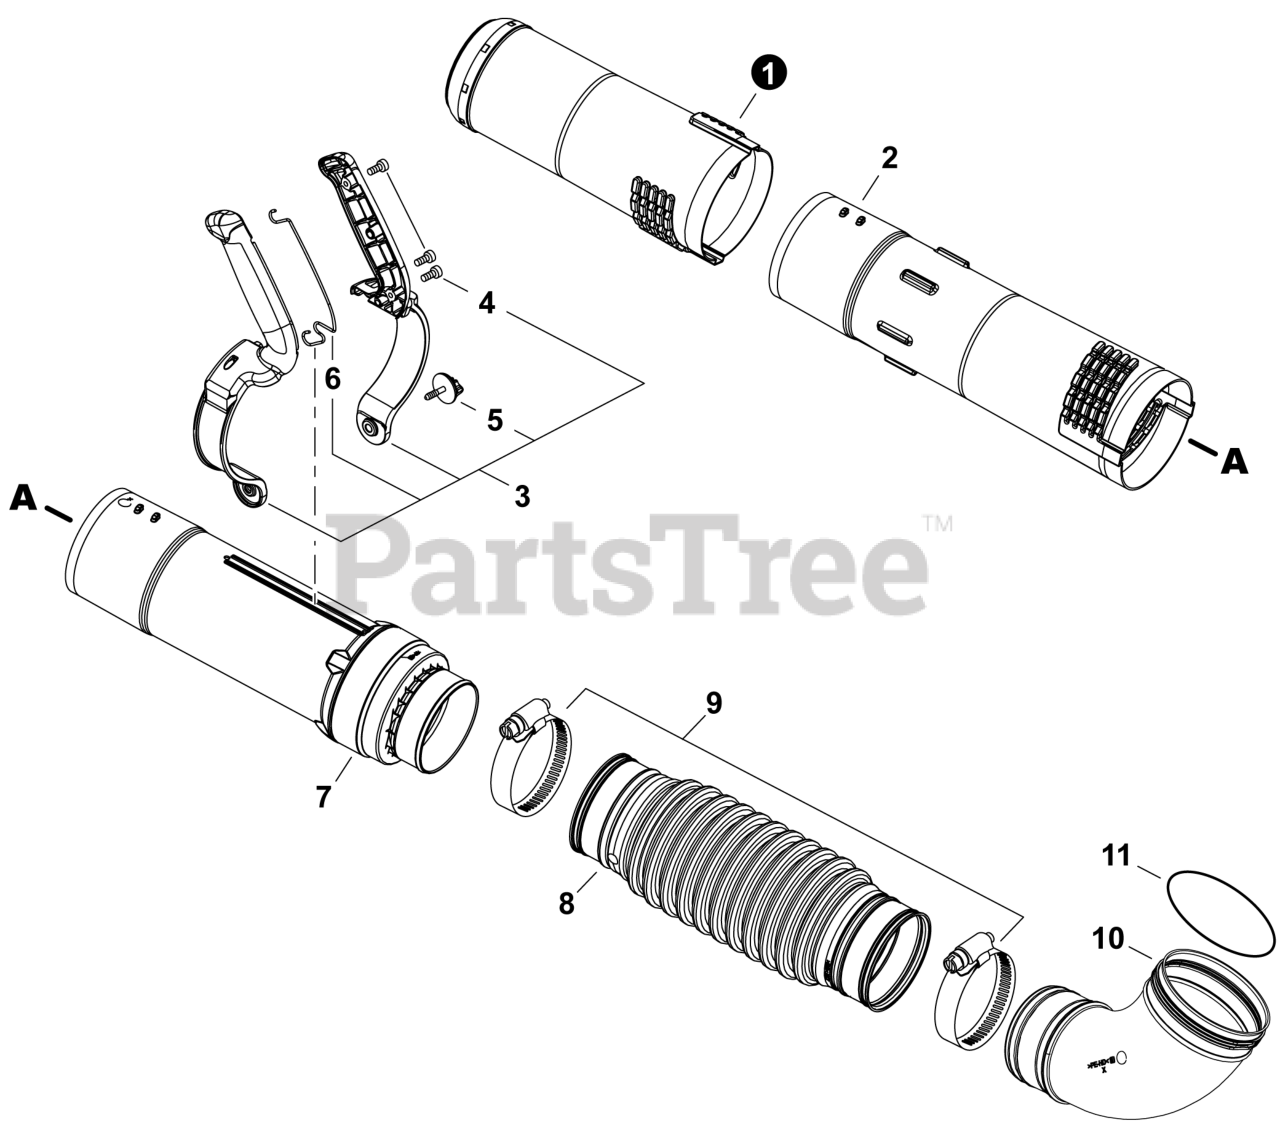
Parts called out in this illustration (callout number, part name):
1	TUBE, BLOWER - NOZZLE
2	TUBE, BLOWER - STRAIGHT
3	HANDLE KIT - BLOWER TUBE
4	BOLT, TORX 4×12
5	KNOB, FASTENER
6	PLATE, GROUND
7	TUBE, BLOWER - SWIVEL
8	TUBE, BLOWER - FLEXIBLE
9	CLAMP - BAND
10	TUBE, BLOWER - ELBOW
